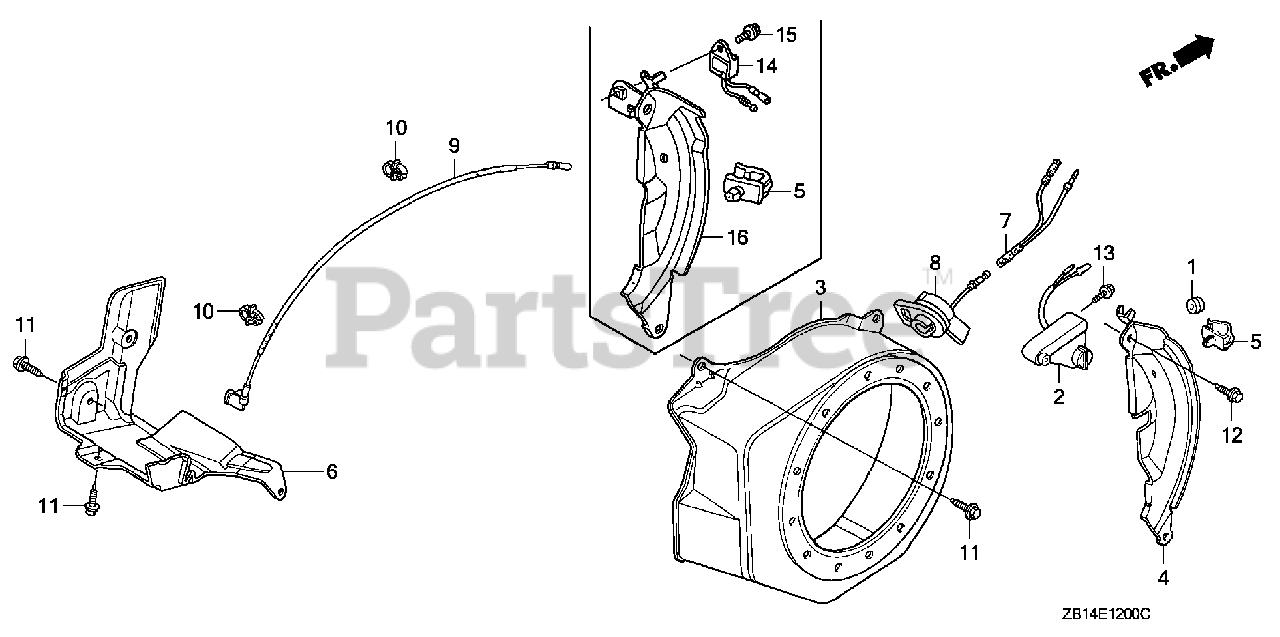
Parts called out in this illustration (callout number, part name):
3	COVER, FAN *NH1* (BLACK)
5	CLIP, HARNESS
8	SWITCH ASSY., ENGINE STOP
9	WIRE, STOP SWITCH (370MM)
11	BOLT, FLANGE (6X12) (CT200)
12	BOLT, FLANGE (6X20) (CT200)
14	ALERT UNIT, OIL
15	BOLT, FLANGE (6X8)
16	PLATE, SIDE (ALERT & LAMP)
